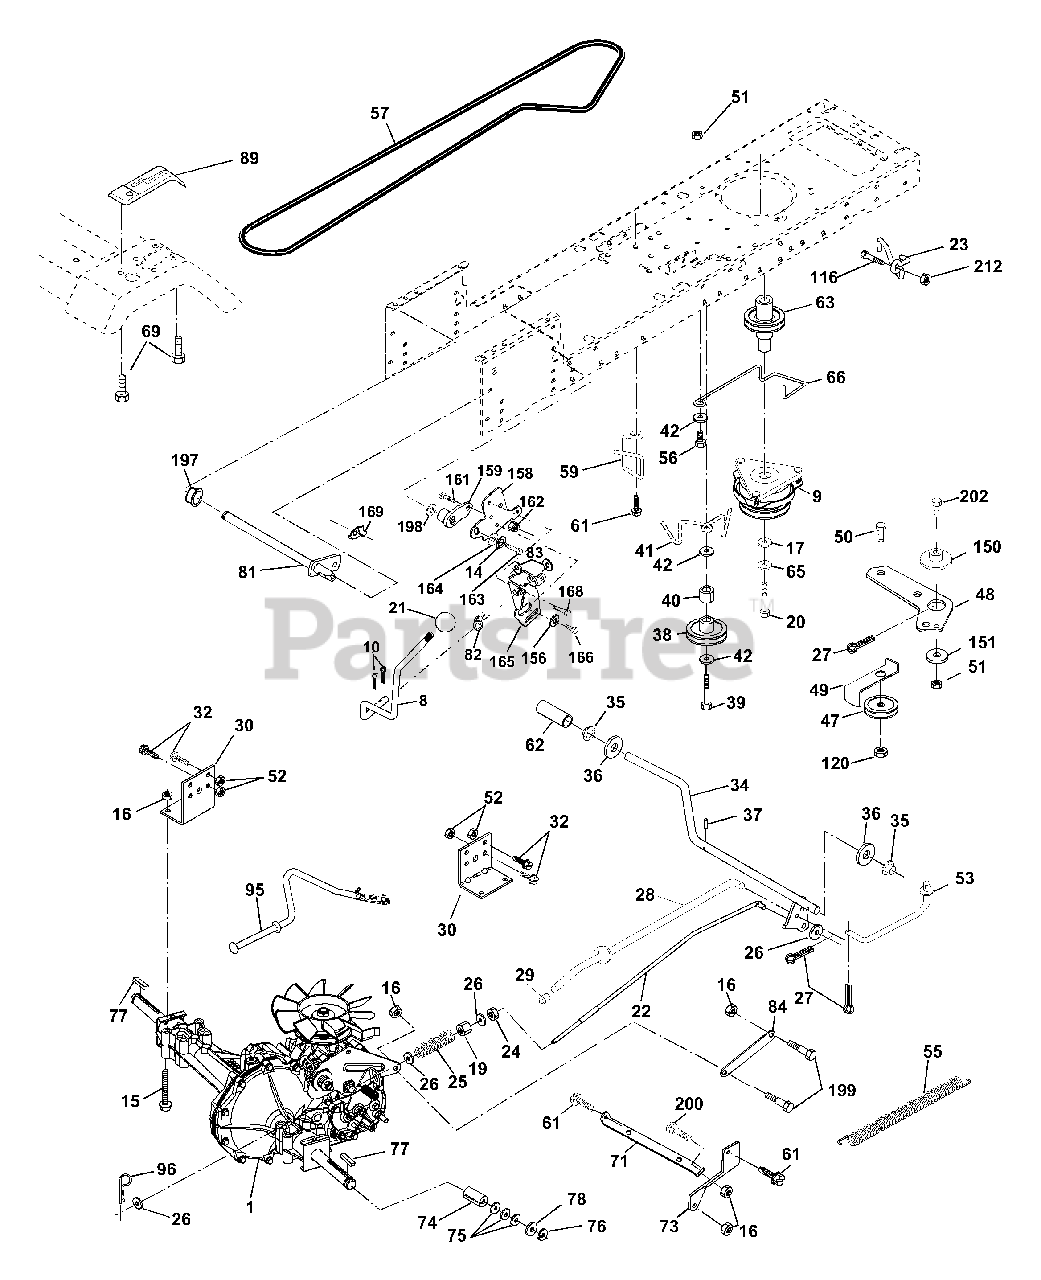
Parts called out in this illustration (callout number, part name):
8	Rod Shift Fender Adjust STLT
9	Clutch Elecric
10	Pin Cotter 1/8 x 1 CAD
14	Washer Lock Hvy Helical
15	Bolt Hex 5/16-18 Unc Flghd
16	Nut Lock Hex W/Ins. 5/16-18 Unc P
17	Washer 1-1/2 x 15/32
19	Nut Lock Hex W/Ins 3/8-16 Unc
20	Bolt, Hex 7/16-20 x 4-1/4 Ga. 5
21	Knob Deluxe 1/2-13 UNC BLK/BLK
22	Rod, Brake Hydro
23	Bracket Asm Mtg CL
24	Nut Hex Jam 3/8-16 UNC
25	Spring, Brake Rod
26	Washer
27	Pin Cotter 1/8 x 3/4 CAD.
28	Rod, Parking Brake
29	Cap,Parking Brake
30	Bracket, Transaxle
32	Bolt Hex Hd 5/16-18 Unc x 3/4
34	Shaft, Foot Pedal
35	Bearing, Nylon
37	Pin, Roll
38	Pulley, Composite, Flat
39	Bolt, Fin, Hex 3/8-16 x 3
40	Spacer Split
41	Keeper, Belt Idler
42	Washer 13/32 x 13/16 x 12 Ga
47	Pulley, Idler, V-Groove Plastic
48	Bellcrank Clutch Grnd Drv STL
49	Retainer, Belt Style Spring
50	Bolt Hex Hd 3/8-16 Unc x 1-1/2
52	Nut Crown Lock 5/16-18
53	Link, Clutch
55	Spring, Return, Clutch
56	Screw 3/8-16 x 1.0
57	V-Belt, Ground Drive
59	Keeper, Center Span
61	Screw 3/8-16 x 3/4
62	Cover, Pedal
63	Pulley, Clutch Elect
65	Washer Lock Hvy HLCL Spr 7/16
66	Keeper Belt Engine
69	Screw Hex Wsh Hi-Lo 1/4-1/2 Unc
71	Strap Torque Lh Hydro
73	Strap Torque Rh Hydro
74	Spacer, Axle
75	Washer 25/32 x 1-1/4 x 16 Ga.
77	Key, Square
78	Washer 25/32 x 1-5/8 x 16 Ga
81	Shaft Asm Cross Tapered
82	Spring Torsion T/A
83	Washer 17/32 x 3/4 x 16 Ga.
84	Link Transaxle
89	Console, Shift
95	Control Asm. Bypass Hydro
96	Retainer Spring 1" Zinc/Cad
116	Bolt 3/8-16 x 1
120	Nut Lock Flg 3/8-16
150	Spacer Retainer
151	Washer 13/32 x 2 x 10 Ga.
156	Washer Srrted 5/16ID x 1.125
158	Bracket Shift Mount
159	Hub Tapered Flange Shift Lt
161	Bolt Rdhd Sqnk 1/4-20 x 3/4 Gr 5
162	Nut Crownlock 1/4-20 Unc
163	Bolt Hex Fin 1/4-20 Unc x 1 Gr 5
164	Washer 5/8 x .281 x 10 Ga
165	Bracket Pivot Lever
166	Screw 5/16-18 x 5/8
168	Bolt Shoulder 5/16-18 x .561
169	Plate Fastening STLT/CRD
197	Nyliner Snap 5/8" ID
198	Washer Nyl 7/8 ID x .105 Hyd
199	Bolt Shoulder 5/16-18 Unc
200	Bolt Rdhd Sqnk 5/16-18 Unc x 1
212	Nut Hex Flange Lock
